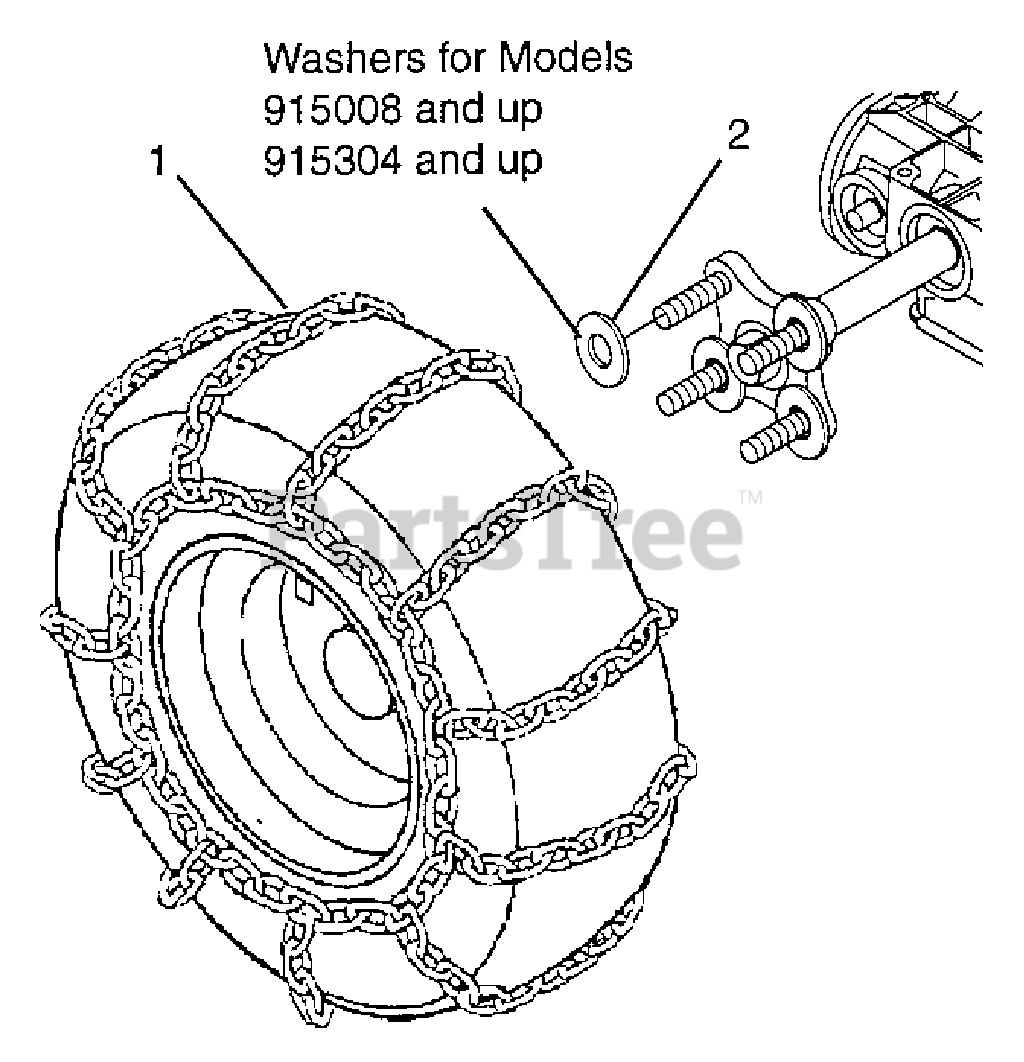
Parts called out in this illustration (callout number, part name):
1	Tire Chains 18 x 8.50 x 8 (1 Pair)
2	Washer-Flat-Steel .531 x 1.06 x .095
3	Wheel Spacer
4	Nut-Lock Center .50-20
6	Adhesive Sealant
